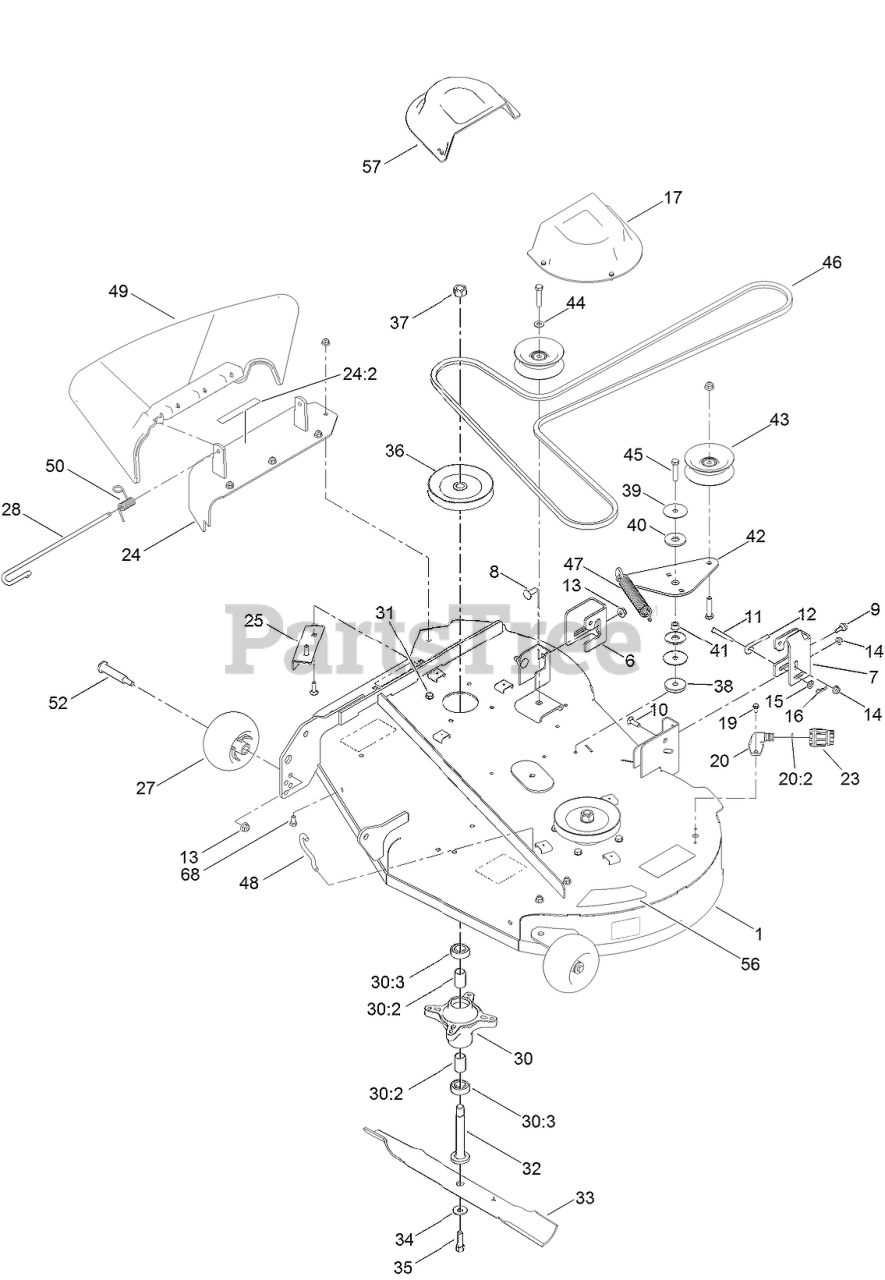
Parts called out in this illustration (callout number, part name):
1	42 INCH DECK ASM
6	BRACKET-HANGER, RH
7	BRACKET-HANGER, LH
8	BOLT-CARR
9	SCREW-SHOULDER,HWH
10	SCREW-CARR
11	PIN-CLEVIS
12	ROD-LEVEL, DECK
13	NUT-HF, NI
14	NUT-HF, NI
15	WASHER-PLAIN
16	PIN-COTTER
17	COVER-BELT
19	SCREW-HWH
20	FITTING-WASHOUT
20:2	O-RING
23	CONNECTOR-HOSE
24	COVER ASM W/DECAL
24:2	DECAL-DANGER
25	BAFFLE-CUTOFF
27	ROLLER-SCALP, ANTI
28	PIN-CHUTE
30	SPINDLE ASM
30:2	SPACER
30:3	BEARING-BALL
31	SCREW-TAPTITE
32	SHAFT-SPINDLE
33	BLADE-HIGH LIFT
34	WASHER-BELLEVILLE
35	SCREW-HH
36	PULLEY
37	NUT-HEX
38	WASHER-PLAIN
39	WASHER
40	WASHER-FRICTION, COMPOSITE
41	SPACER
42	ARM-IDLER
43	PULLEY-IDLER, FLAT
44	WASHER-FLAT
45	SCREW-HH
46	V-BELT
47	SPRING-EXTENSION
48	HOOK-RETURN, SPRING
49	DEFLECTOR-DISCHARGE
50	SPRING-TORSION
52	BOLT-SHOULDER
56	DECAL-DECK
57	SCREW-TAPTITE
68	SCREW-HH
